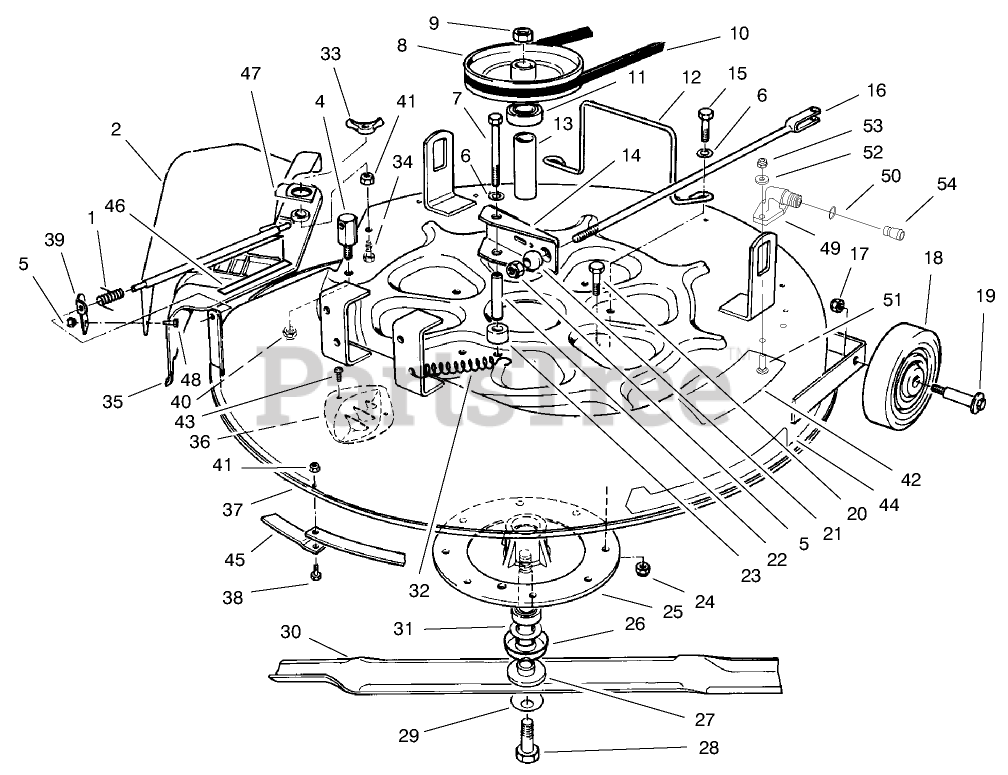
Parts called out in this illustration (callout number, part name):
1	SPRING
2	Deflector
4	POST-PIVOT
5	NUT-HEX
6	WASHER-PLAIN
7	SCREW-HH
8	PULLEY-DECK
9	NUT-HEX
10	V-BELT
11	BEARING-BALL
12	GUIDE-DECK BELT
13	SPACER-BEARING
15	SCREW-HH
16	DECK BRAKE ROD WA
17	NUT-LOCK, NI
18	WHEEL-DECK
20	SCREW-HH
21	BALL-SWIVEL, STOP
23	SPACER-DECK BRAKE
24	NUT-LOCK, NI
25	CASTING-SPINDLE
26	SHIELD-BEARING
27	SHAFT-SPINDLE
28	SCREW-HH
29	WASHER-BELLEVILLE
31	SPACER
32	SPRING-EXTENSION
34	SCREW-HHF
35	COVER- 25" (W/KICKER)
36	KICKER
37	BEARING
38	SCREW-HH
39	BRACKET-DEFLECTOR
41	NUT-LOCK, NI
42	DECAL - DANGER
43	SCREW-PPH
44	DECAL - RECYCLER 25"
45	25" RECYCLER RING
46	DECAL-DANGER, DEFLECTOR
48	SCREW-HH
50	O-RING
51	BOLT-CARR
52	WASHER-FLAT
53	NUT-LOCK, NI
54	CONNECTOR-HOSE
